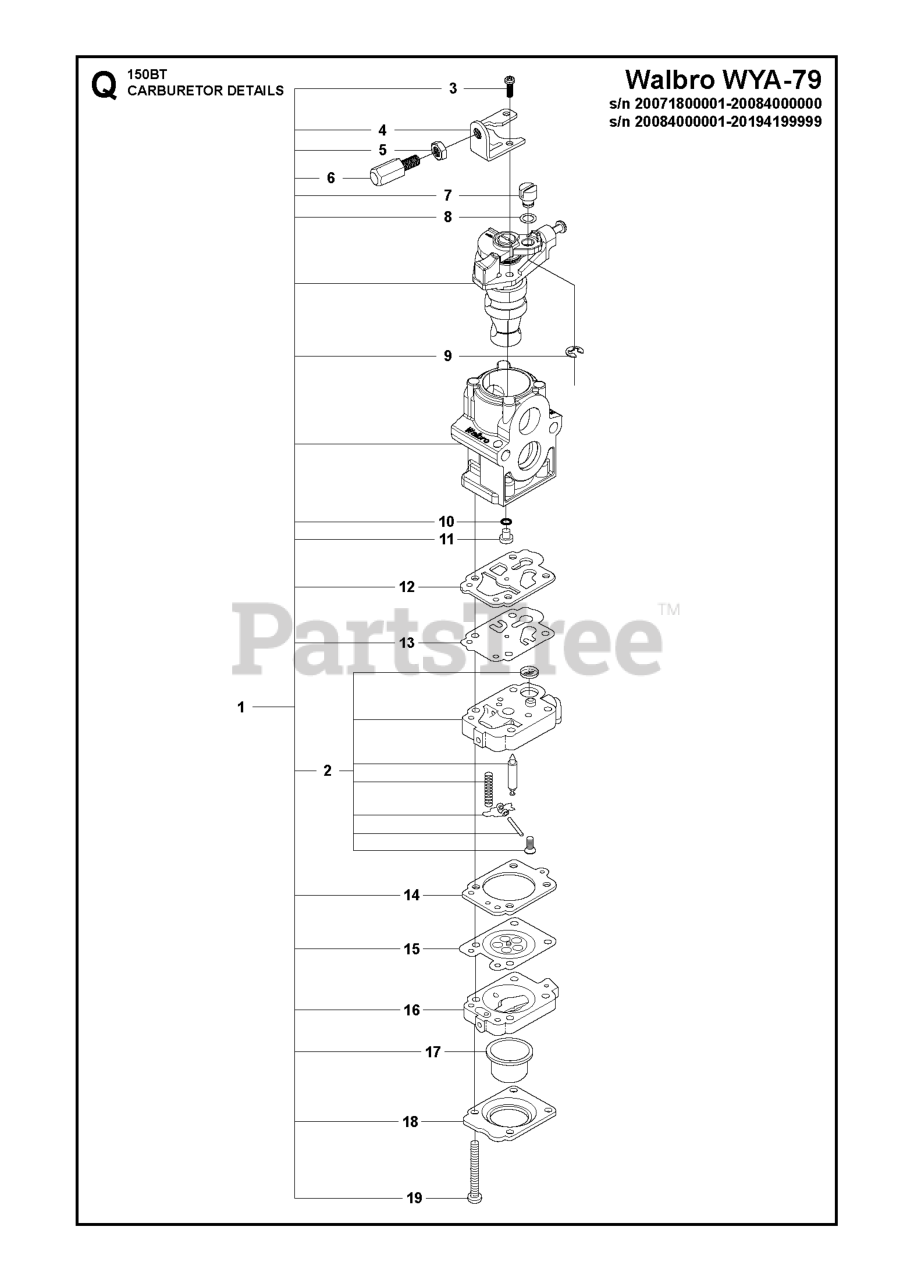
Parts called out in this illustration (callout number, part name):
1	CARBURETOR
2	BODY-A-PUMP
3	SCREW
4	RP_BRACKET
5	NUT
6	SCREW
7	SWIVEL
8	WASHER
10	O-RING
11	JET
12	GASKET
13	DIAPHRAGM
14	GASKET
15	DIAPHRAM
16	BODY
17	PUMP
18	COVER
19	SCREW
